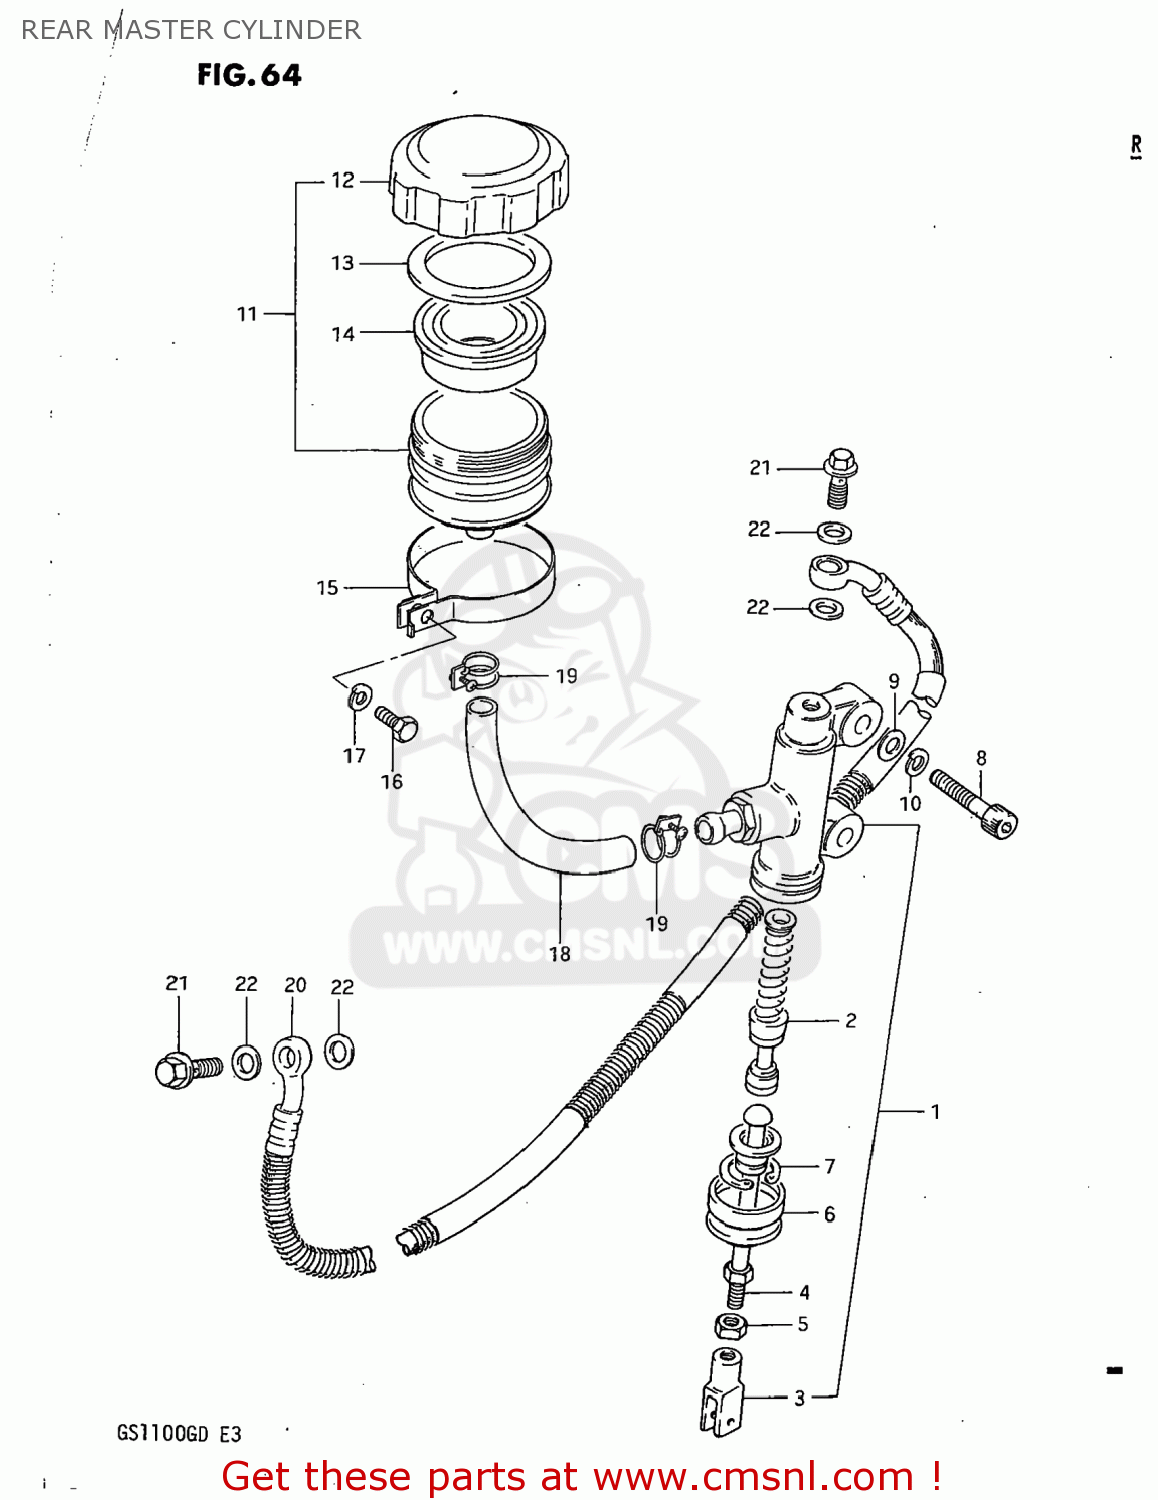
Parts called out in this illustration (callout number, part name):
1	CYLINDER ASSY,RR MASTER
2	PISTON/CUP SET
3	YOKE
4	ROD,REAR MASTER CYLINDER
5	NUT,MASTER CYLINDER
6	BOOT
7	CIRCLIP
8	BOLT
9	WASHER
10	WASHER,LOCK,8.
11	TANK ASSEMBLY,RESERVOIR
12	CAP
13	PLATE,DIAPHRAGM
14	DIAPHRAGM
15	CLAMP
16	BOLT, UPPER
17	LOCK WASHER
18	HOSE,RESERVOIR TANK
19	CLAMP
20	HOSE,REAR BRAKE
21	BOLT,UNION
22	WASHER
